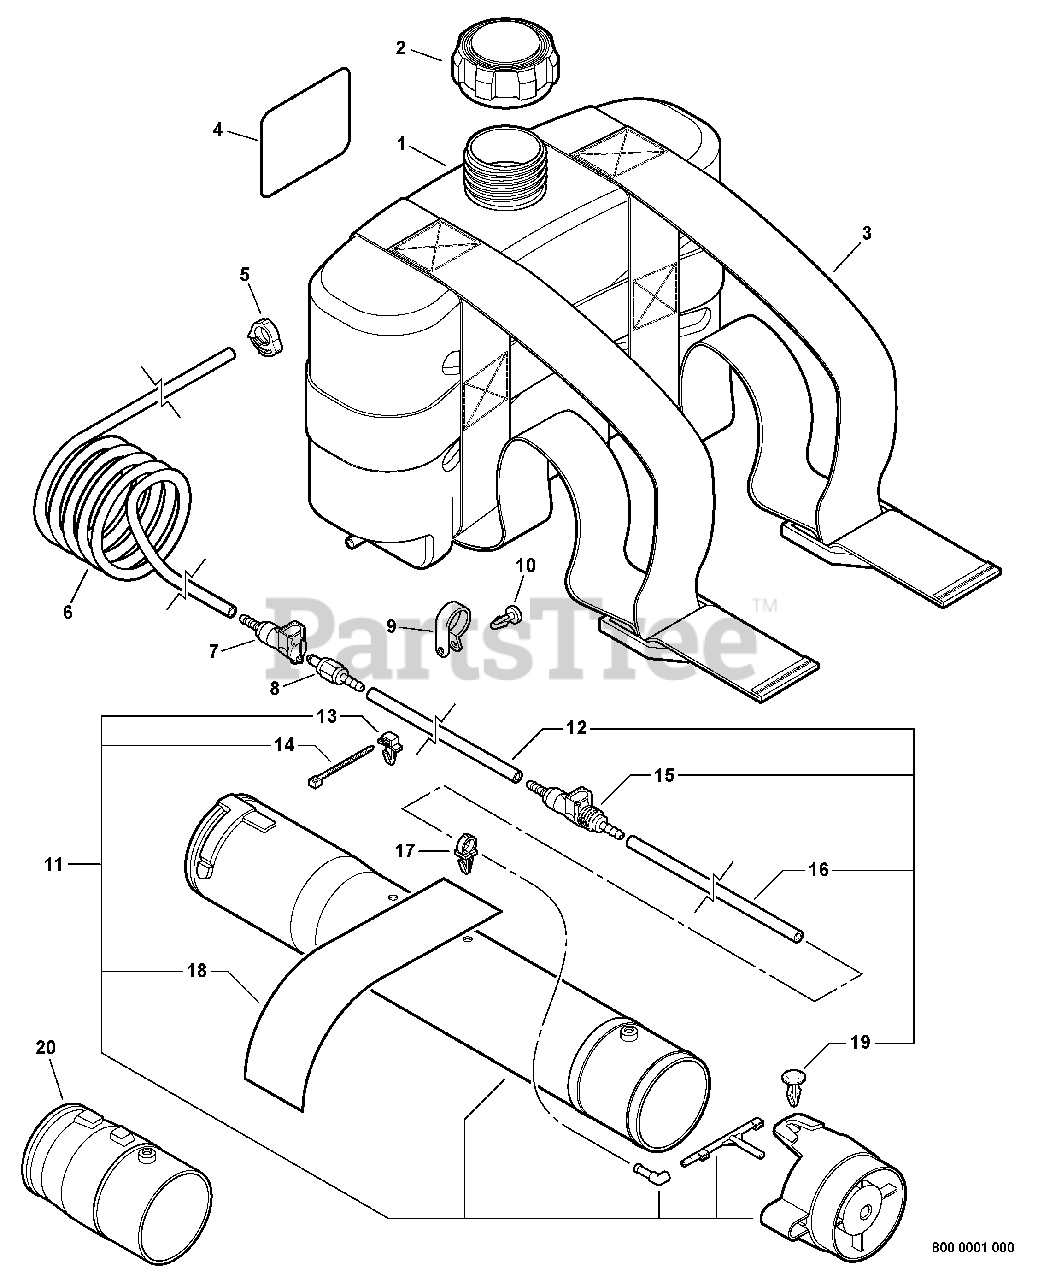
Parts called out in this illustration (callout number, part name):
1	TANK, CHEMICAL
2	CAP, TANK
3	STRAP, BACKPACK
4	LABEL - YARD SHIELD
5	CLAMP, HOSE
6	HOSE, COILED
7	COUPLING - FEMALE
8	COUPLING - MALE
9	CLAMP
10	CLIP
11	SPRAYER PIPE ASSY
12	HOSE - 11in.
14	TIE, CABLE
15	VALVE, SHUTOFF
16	HOSE - 24in.
18	LABEL - OPERATION
20	ADAPTOR
